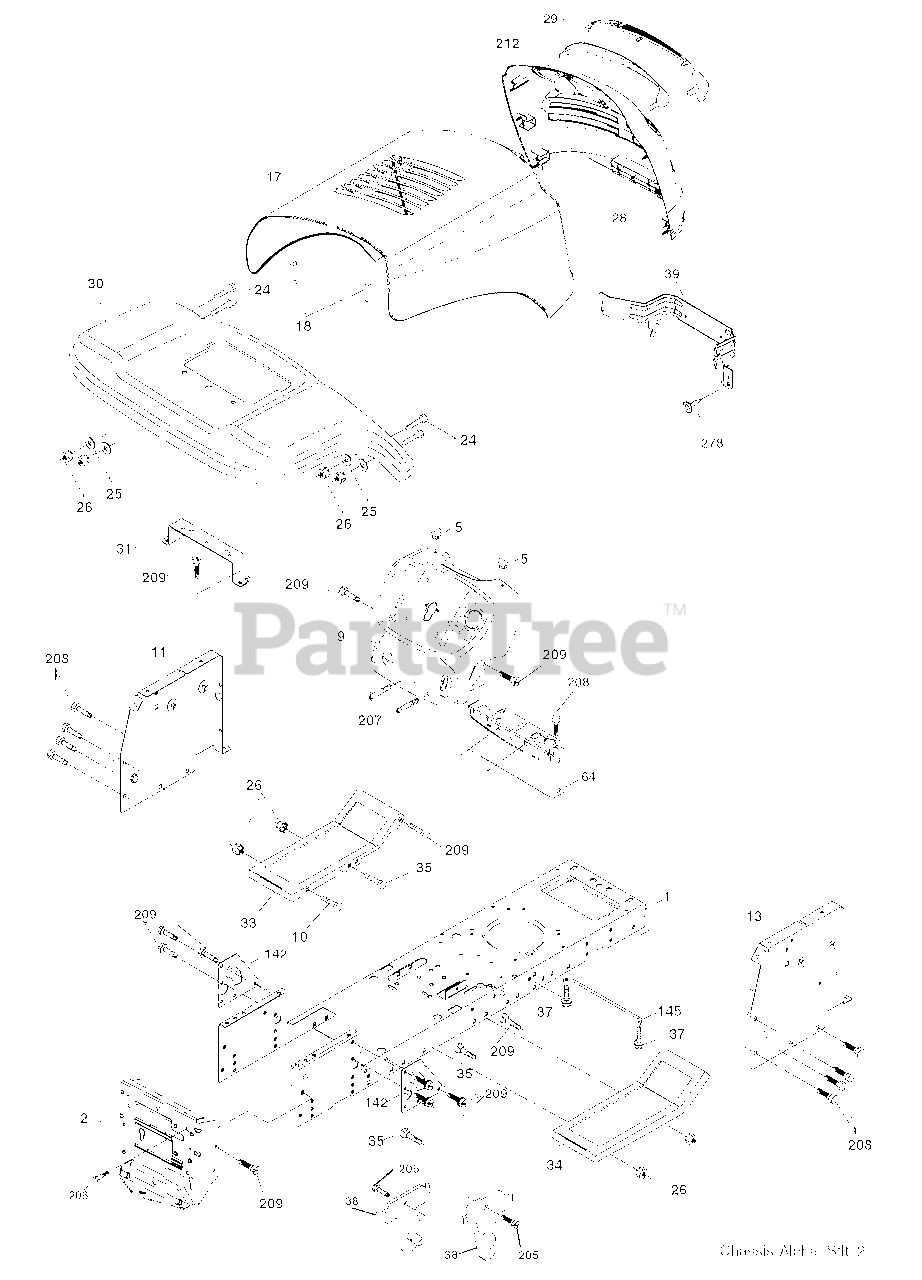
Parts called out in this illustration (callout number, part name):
1	Chassis
2	Drawbar, Stretch
5	Bumper, Hood/Dash
9	Dash
10	Bolt, Carriage 3/8-16 x 1
11	Panel Dash LH
13	Panel Slkscr Dash RH
17	Hood
18	Bumper Hood
24	Bolt Fin Hex 3/8-16 unc x 1 Gr. 5
25	Washer 13/32 x 13/16 x 12 Ga.
26	Nut Lock Hex w/Ins 3/8-16 unc
28	Grille/Lens Asm.
29	Lens Grille Bar
30	Fender
31	Bracket Fender Repl 109873X
33	Footrest Pnt LH
34	Footrest Pnt RH
35	Bolt Rdhd Sht Sqnk 3/8-16 x 3/4
37	Screw Thdrol 5/16-18 x 1/2 TYT
38	Bracket Asm. Pivot Mower
39	Bracket Pivot
64	Dash Lower
142	Plate Reinforcement
145	Rod Pivot Chassis/Hood
205	Screw Thdrol 3/8-16 x 1/2
206	Bolt Shoulder 5/16-18
207	Screw 5/16-18 x 1/2
208	Screw Thdrol 3/8-16 x 1/2
209	Screw Hex Wsh Thdrol 3/8-16
212	Insert Lens Reflect
278	Screw #10 X 0.750 BOS Thread
278	Plug Button Blk 359 Dia Choke
278	Plug Dome Plastic
